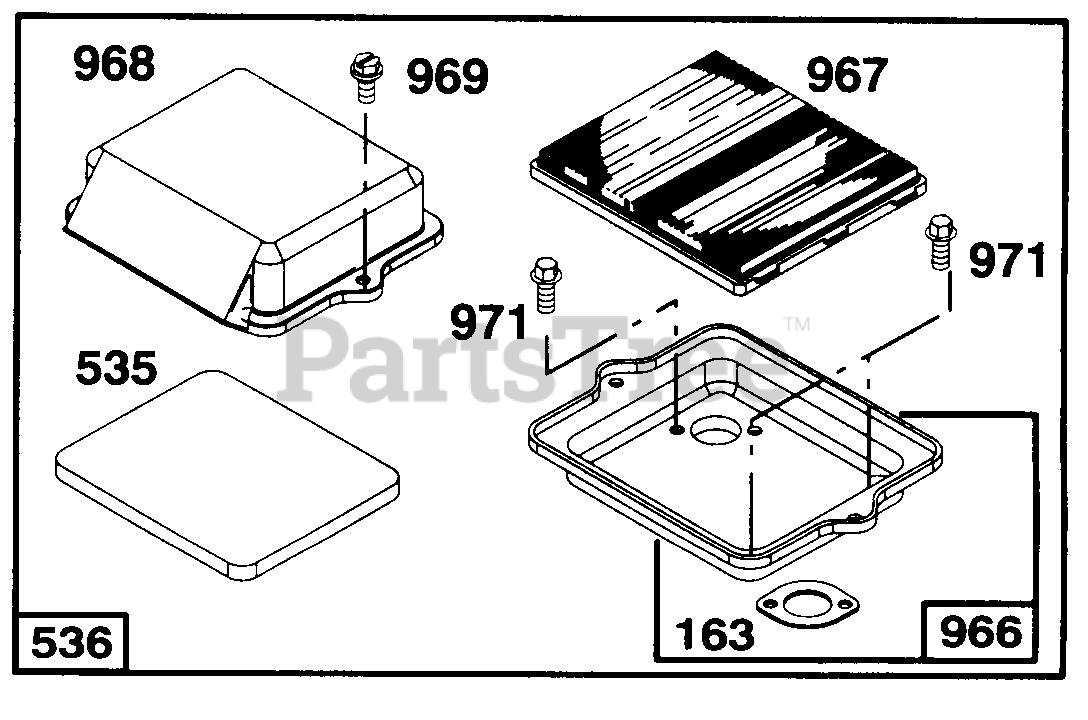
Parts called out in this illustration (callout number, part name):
163	Gasket--Air Cleaner Mounting
535	Element--Air Cleaner
536	Cleaner--Air
966	Base Air Cleaner
967	Filter--Air Cleaner
968	Cover--Air Cleaner
969	Screw--Air Cleaner
971	Screw--Hex Hd.
